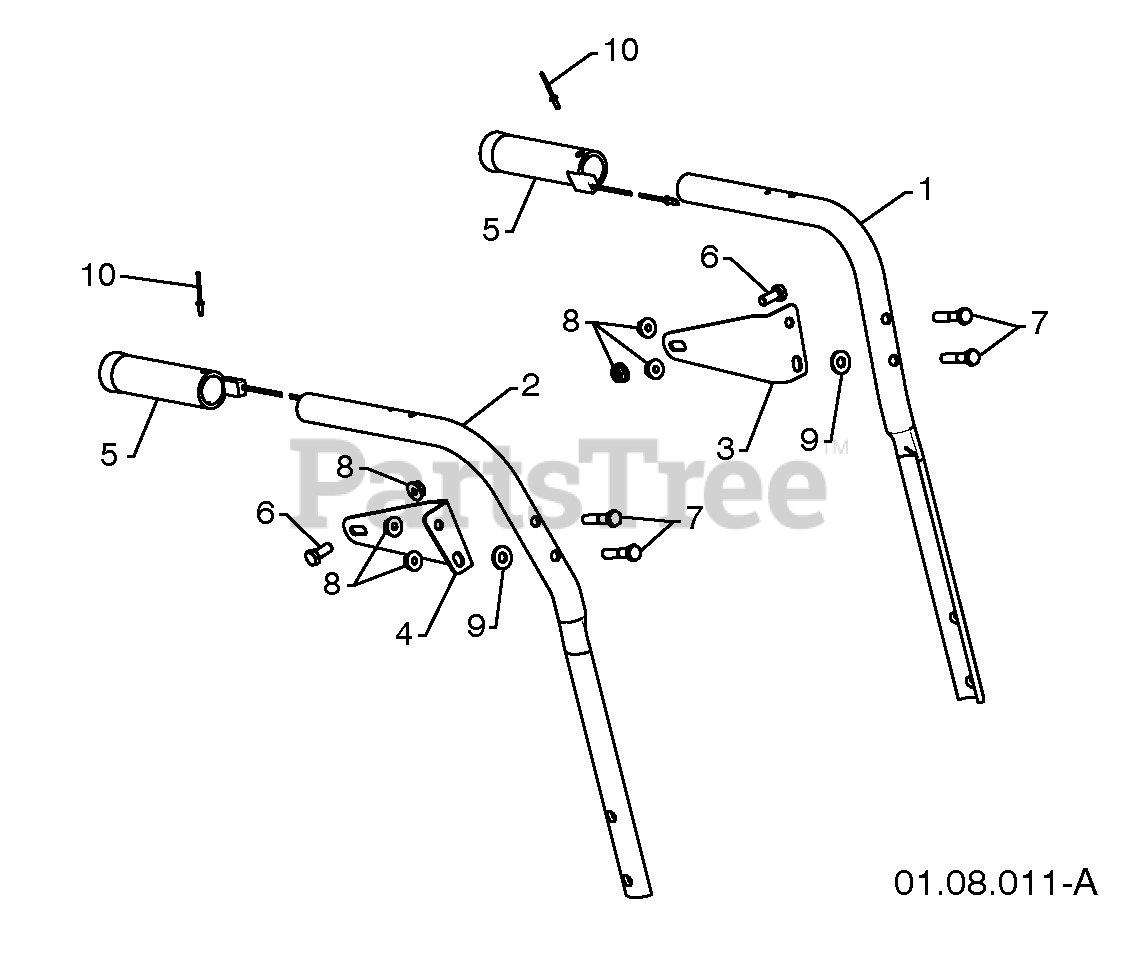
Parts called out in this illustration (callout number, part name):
1	PLOW HANDLE LH
2	PLOW HANDLE RH
3	PANEL BRACKET LH
4	PANEL BRACKET RH
5	HEATED HANDLE GRIP
6	SCREW 5/1618 X .750
7	SCREW 5/1618 X 1.50
8	NUT 5/1618
10	POP RIVET 1/8
